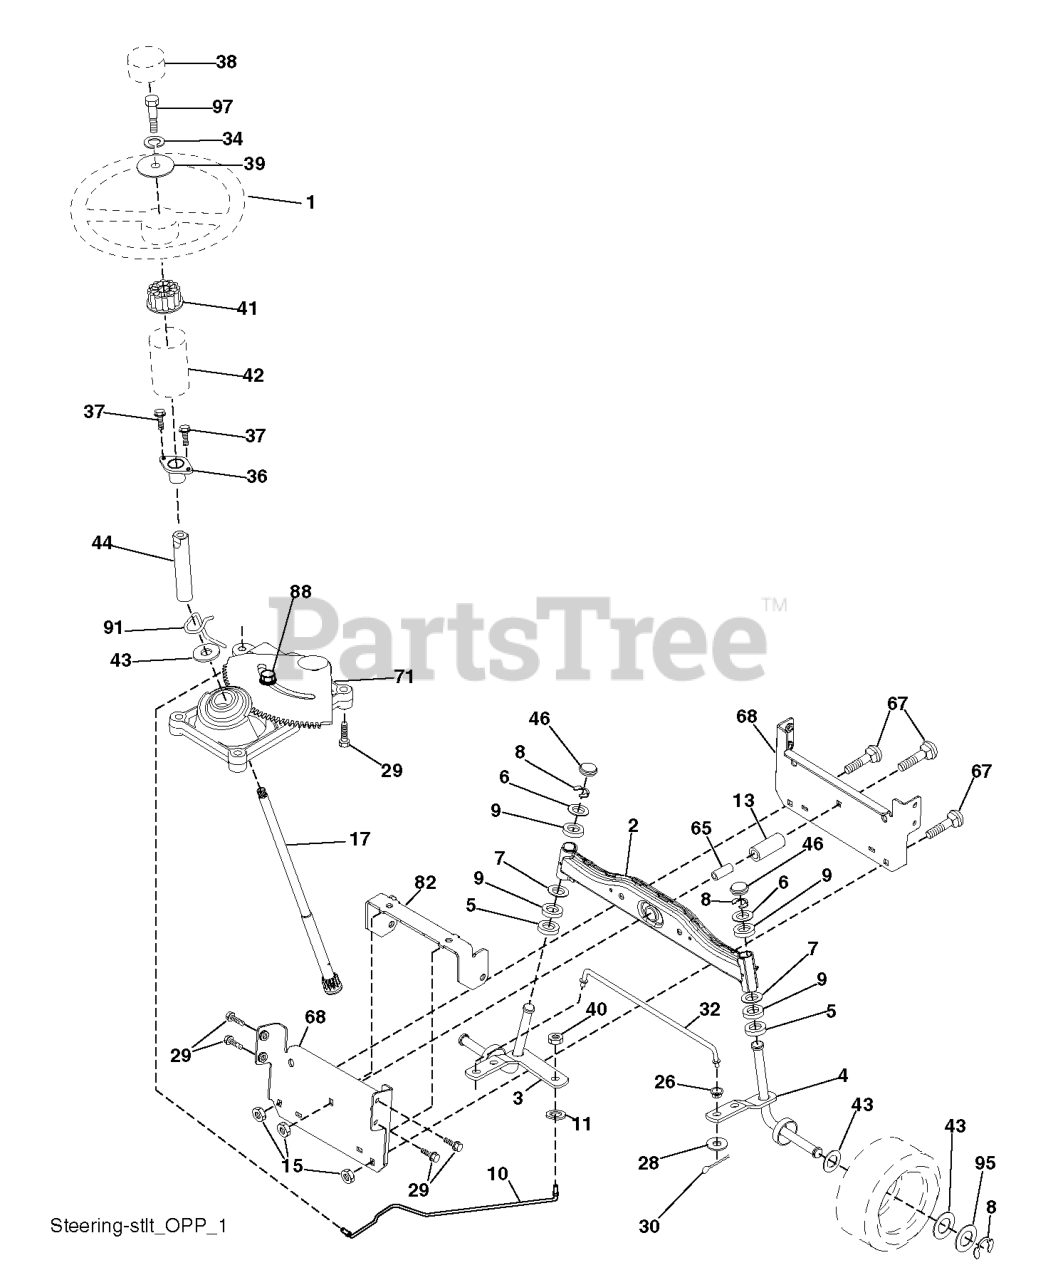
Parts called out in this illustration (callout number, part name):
1	WIRE.ASM.INNER.SP
2	SHAFT.ASM.LIFT.RH.INF
3	PIN.GROOVE.5/16
4	RETAINING RING LT
6	BEARING.NYLON
7	GRIP HANDLE
8	PLUNGER BUT KIT
11	LINK LIFT LH
12	LINK LIFT RH
13	RETAINER-SPRNG RB
15	LINK.SUSPENSION.FRONT
16	NUT.HEX.JAM.1/2-13
18	NUT.LK.W/WSH.1/2.
19	ARM.REAR.SUSPENSION
20	SPRING RETAINER
26	RETAINER CLIP
27	ROD ADJ LIFT
28	NUT
29	KNOB INF 3/8-16
31	BEARING.PIVOT.LIFT
32	NUT CROWNLOCK 3/8-24
36	POINTER, HEIGHT INDICATOR(2 2)
38	SCREW 5/16-18X1
41	IND. HEIGHT STLT
49	NUT
50	NUT PUSH M
